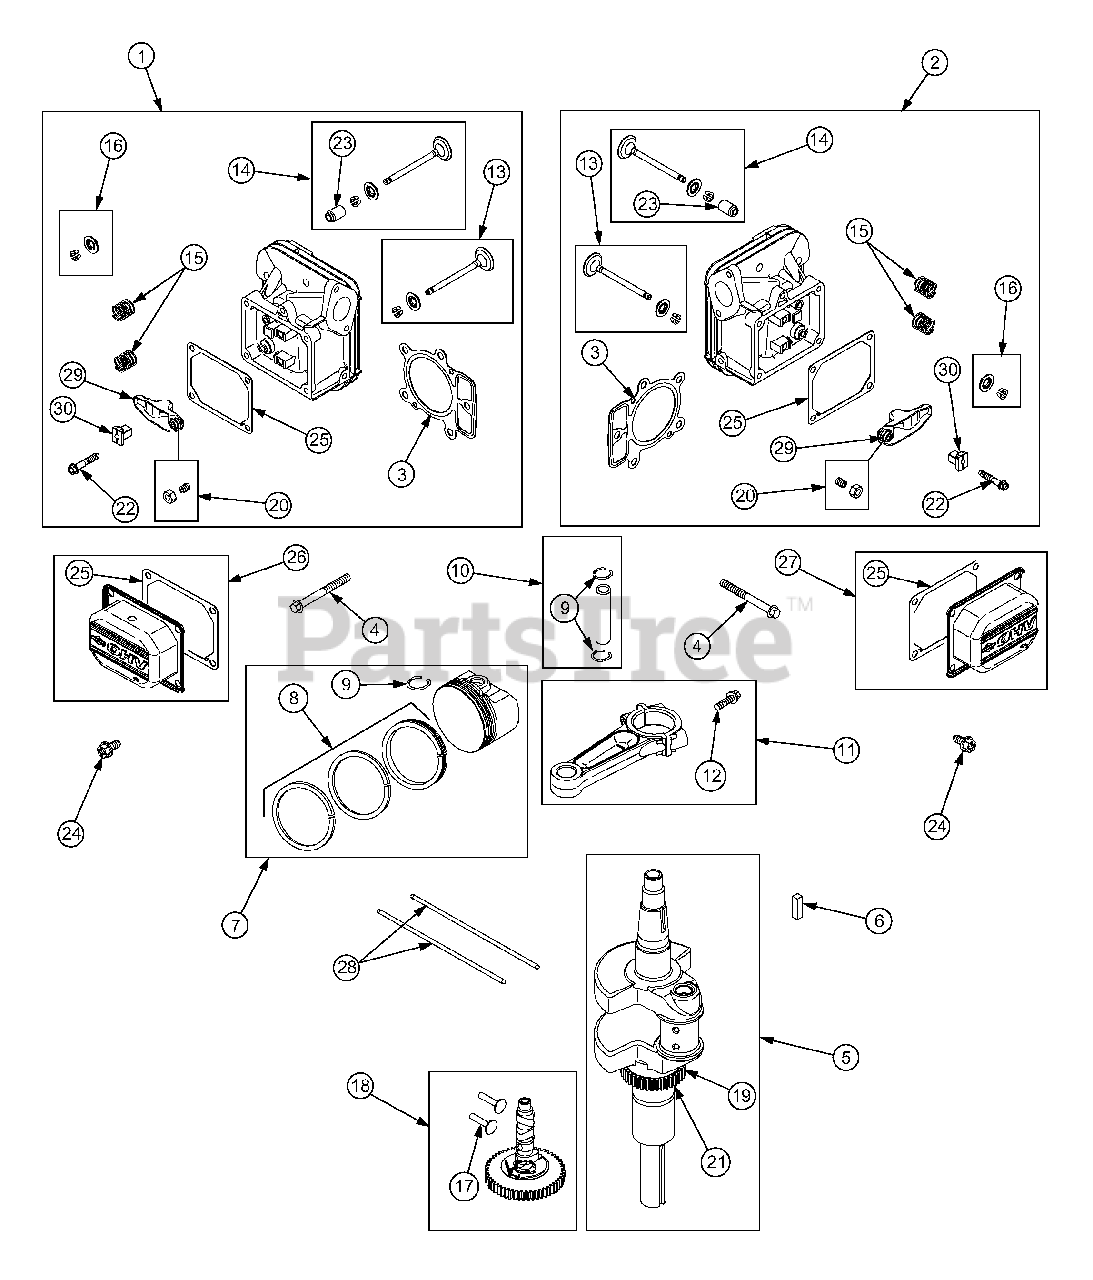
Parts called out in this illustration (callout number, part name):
1	Head, Cylinder (Cylinder 1)
2	Head, Cylinder (Cylinder 2)
3	Gasket, Cylinder Head
4	Screw, (Cylinder Head)
5	Crankshaft
6	Key, Flywheel
7	Piston Assembly (Standard)
8	Ring Set, Piston (Standard)
9	Lock Ring, Piston Pin
10	Pin, Piston
11	Rod, Connecting
12	Screw (Connecting Rod)
13	Valve, Exhaust
14	Valve, Intake
15	Spring, Valve
16	Keeper, Valve
17	Tappet, Valve
18	Camshaft
19	Key, Timing
20	Adjuster, Rocker Arm
21	Gear, Timing
22	Screw (Rocker Arm)
23	Seal, Valve
24	Screw (Rocker Cover)
25	Gasket, Rocker Cover
26	Cover, Rocker (Cylinder 1)
27	Cover, Rocker (Cylinder 2)
28	Rod, Push (Steel)
29	Arm, Rocker
30	Pivot, Rocker Arm
